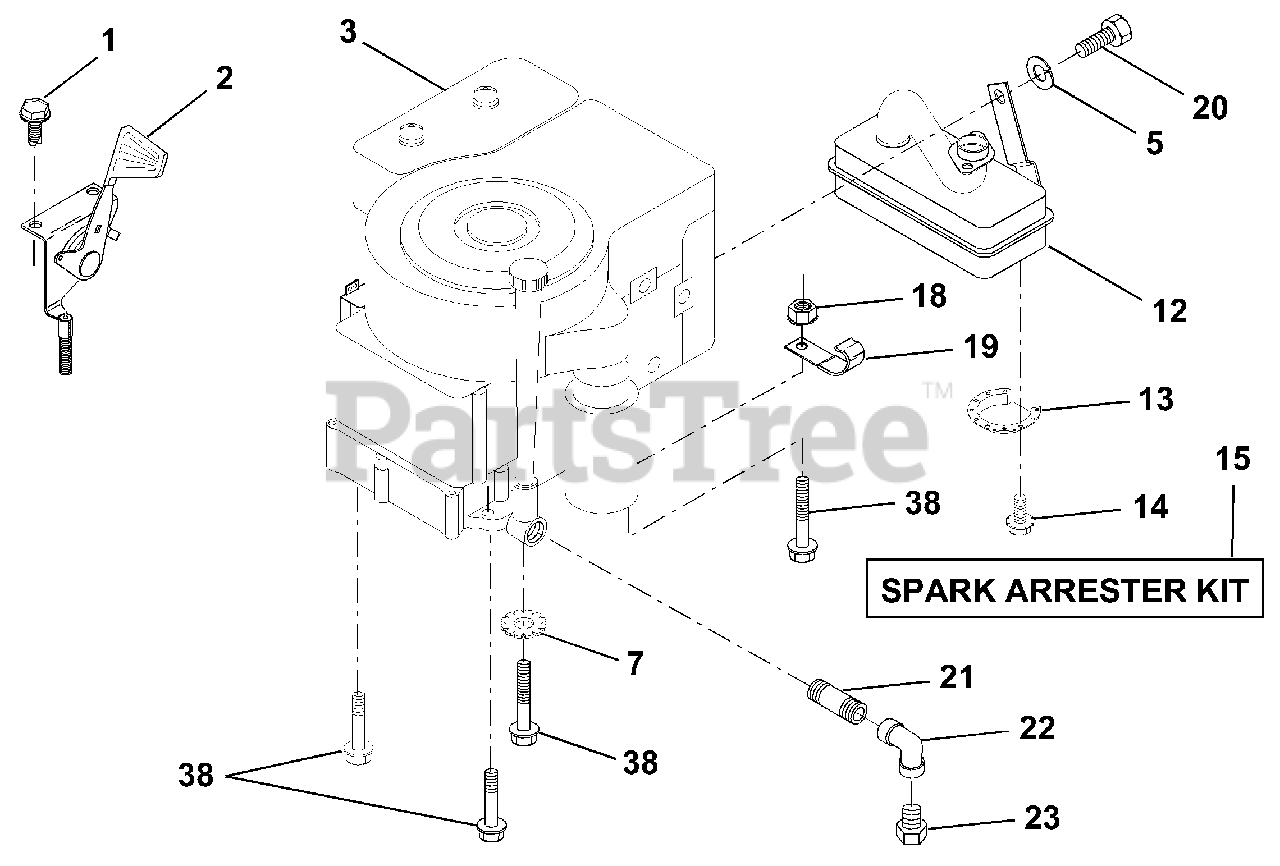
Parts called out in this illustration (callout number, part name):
1	Screw, Hex Head, Thread Cutting 1/4-20 x 1/2
2	Control, Throttle
3	Engine, Kohler, 12.5 HP
5	Washer, Lock, Hvy Hlcl Spring 5/16
7	Washer Lock Ext. Tooth 3/8
13	Deflector Muffler
14	Screw Spiderloc Hex Hd # 8 x 1/2 AB
15	Arrester, Spark
18	Nut, Hex, Keps 3/8-16
19	Clip, Fuel Line
20	Bolt, Hex, Fin. 5/16 - 18 x 1/2
21	Nipple Pipe
22	Elbow
23	Oil Drain Plug
38	Bolt Hex
